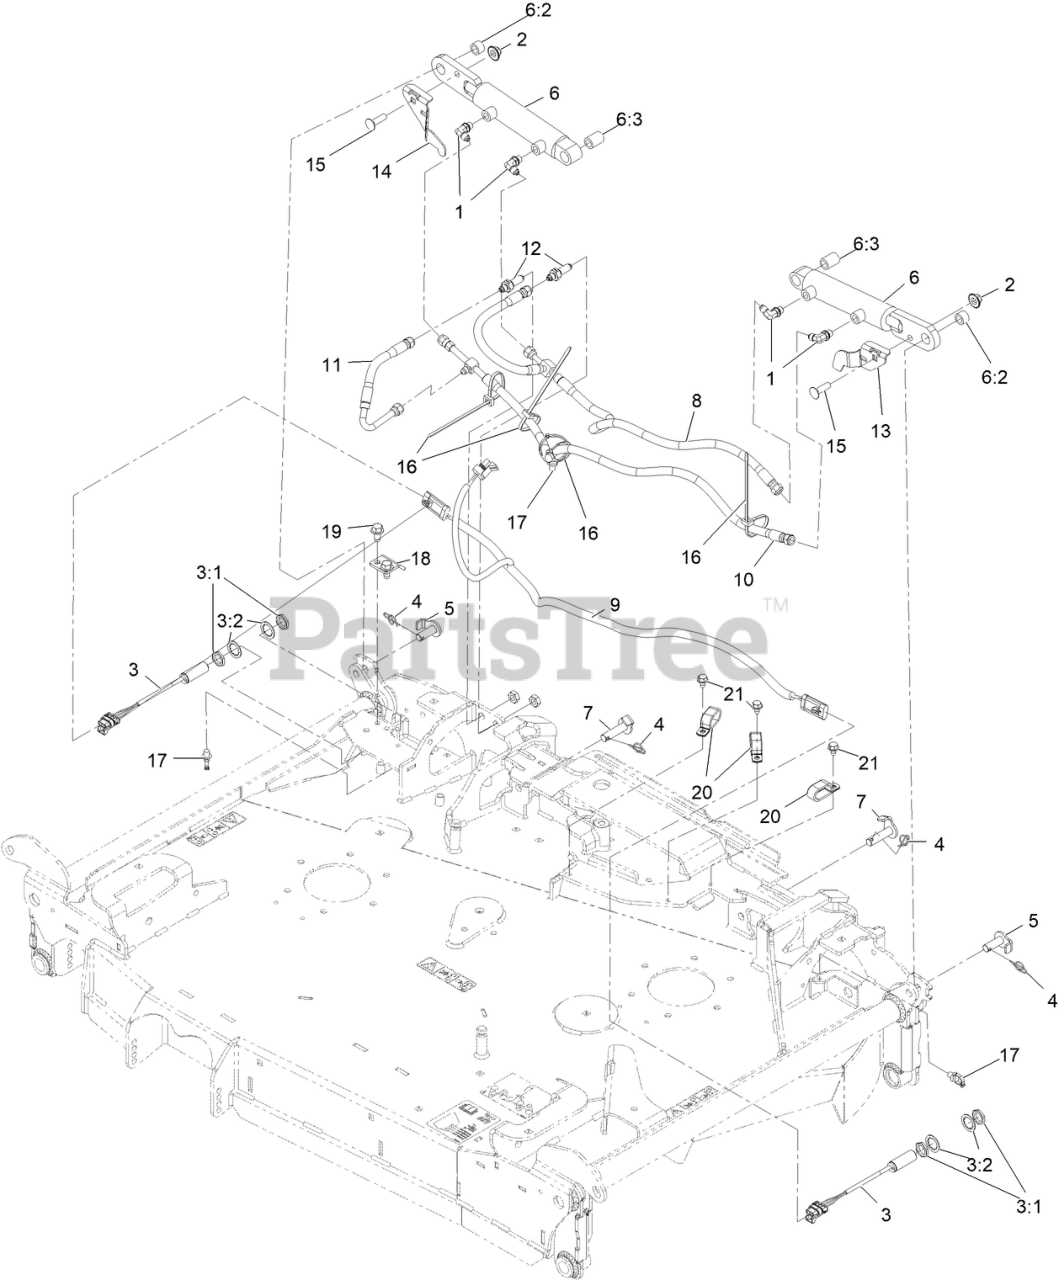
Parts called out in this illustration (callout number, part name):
1	Adapter, 90?
2	NUT-FLANGE, NI
3	PROXIMITY SWITCH ASM
3:1	NUT-HEX
3:2	WASHER-LOCK, INTERNAL TOOTH
4	PIN-COTTER, LOCKING
5	EYE-PIN, CYLINDER
6	DECK FOLD CYLINDER ASM
6:2	BUSHING
6:3	BUSHING
7	PIN-CYLINDER
8	HOSE ASM
9	HARNESS-WIRE
10	HOSE ASM
11	HOSE ASM
12	FITING-STRAIGHT
13	PLATE-PROXIMITY, LH
14	PLATE-PROXIMITY, RH
15	SCREW-CARR
16	TIE-CABLE
17	CLIP-TIE
18	BRACKET-GUARD, SWITCH (RH)
19	SCREW-HWH
21	SCREW
